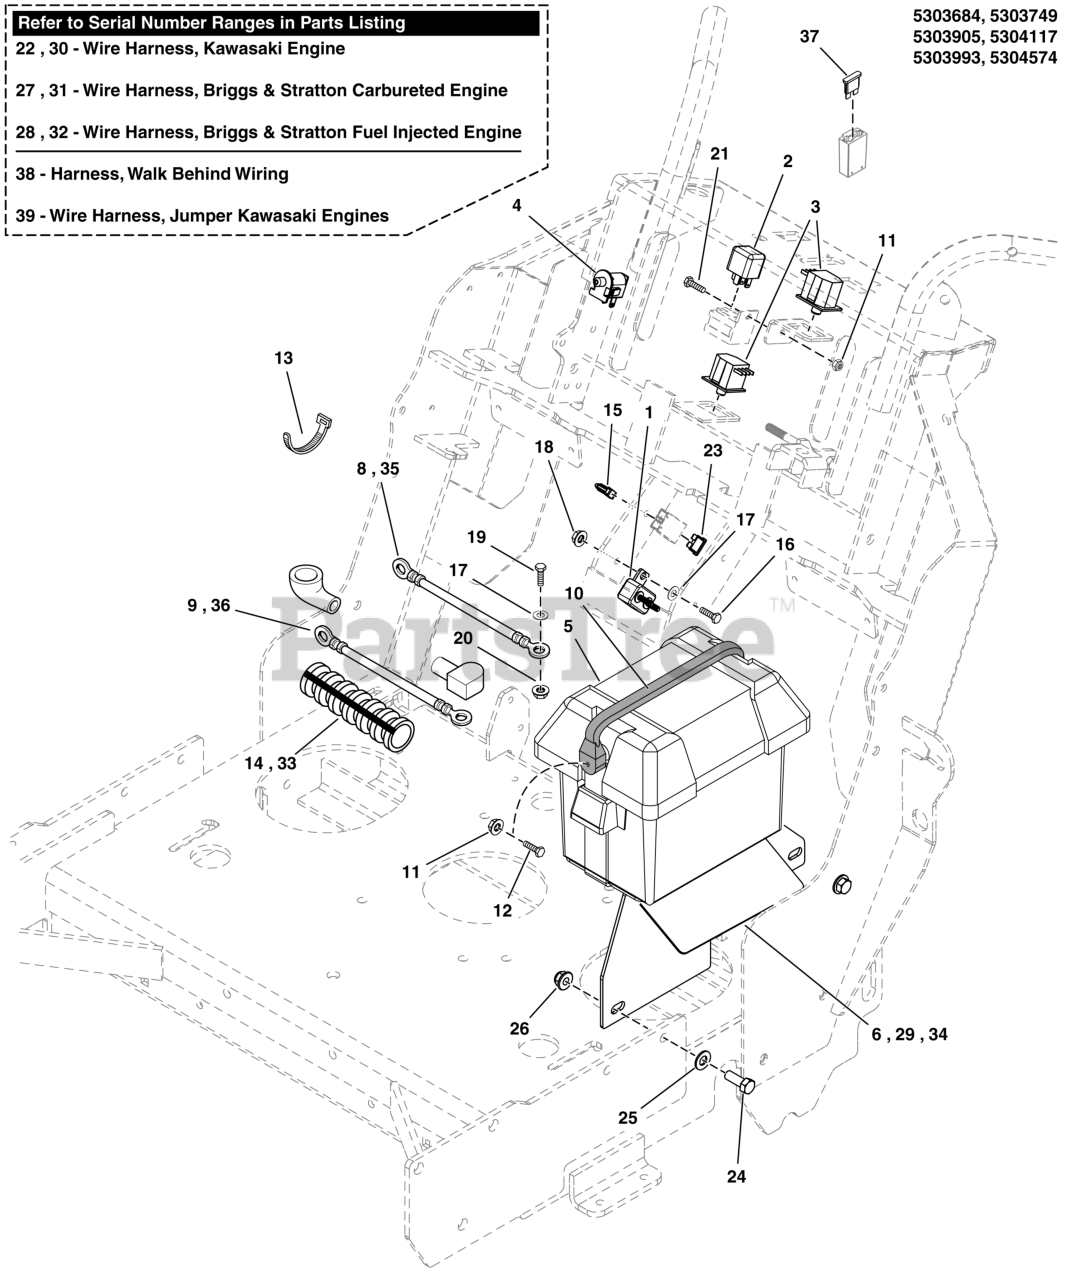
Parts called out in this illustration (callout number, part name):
1	BREAKER-CIRCUIT 12VOLT 20AMPS W/TAB
2	RELAY, 12 VOLT, 40 AMP
3	SWITCH, PLUNGER, NO/NC SNAP-IN, LOW PROFILE
4	SWITCH-PUSH BUTTON OP PRES BLACK SNAP IN
5	BATTERY BOX, W/ DRAIN HOLE
6	WELD, BATTERY MOUNT, SW35 - BLK
8	CABLE, BATTERY, NEG, 30, 1/4-5/16
9	BATTERY CABLE, POS, 35, 1/4-5/16
10	STRAP, RUBBER
11	NUT, Hex, Nylon Lock, #10-24
12	SCREW, #10-24 X 1 RS, CZ
13	TIE, SELF-LOCKING, 12"
14	WIRE LOOM, 3/8 ID X 27" LONG
15	FIR TREE MOUNT, PACKARD
16	BOLT, 1/4"-20 X 3/4" GD5 YZ
17	WASHER, 1/4 SAE
18	NUT, 1/4-20 Hex Nylock Flange
19	HHCS, 1/4-20 X 0.625, GR5, ZINC/CLEAR
20	NUT, 1/4-20 HEX SERR. FLANGE
21	SCREW, #10-24 X 1/2" ROUND PHILLIPS
22	WIRE HARNESS, SW35/FW35 KAWI
22	WIRE HARNESS, SW35, KAWI, NO BRAKE
23	FUSE, ATO-15 (15 AMP)(SV)
24	BOLT, 3/8-16 X 1" GD5 CZ
25	WASHER, 3/8 SAE
26	NUT, 3/8 - 16 HEX NYLOCK FLANGE
27	WIRE HARNESS, SW35, BV, NO BRAKE
28	WIRE HARNESS, SW/FW35 BVE 28
29	WELD, BATTERY MOUNT, W35 - BLK
30	WIRE HARNESS, W35, KAWI, NO BRAKE
31	WIRE HARNESS, W35, BV, NO BRAKE
32	WIRE HARNESS, W35, BVE 28, NO BRAKE
33	WIRE LOOM, 3/8" ID X 29.00 IN
34	WELD, MOUNT-BATTERY, W35 - BLK
35	BATTERY CABLE,NEG, 42, 1/4-5/16
36	BATTERY CABLE, POS, 47, 1/4-5/16
37	FUSE, ATO-20 (20 AMP)(SV)
38	HARNESS, WALK BEHIND, WIRING
39	WIRE HARNESS, JUMPER, KAWI - LARGE HARNE
